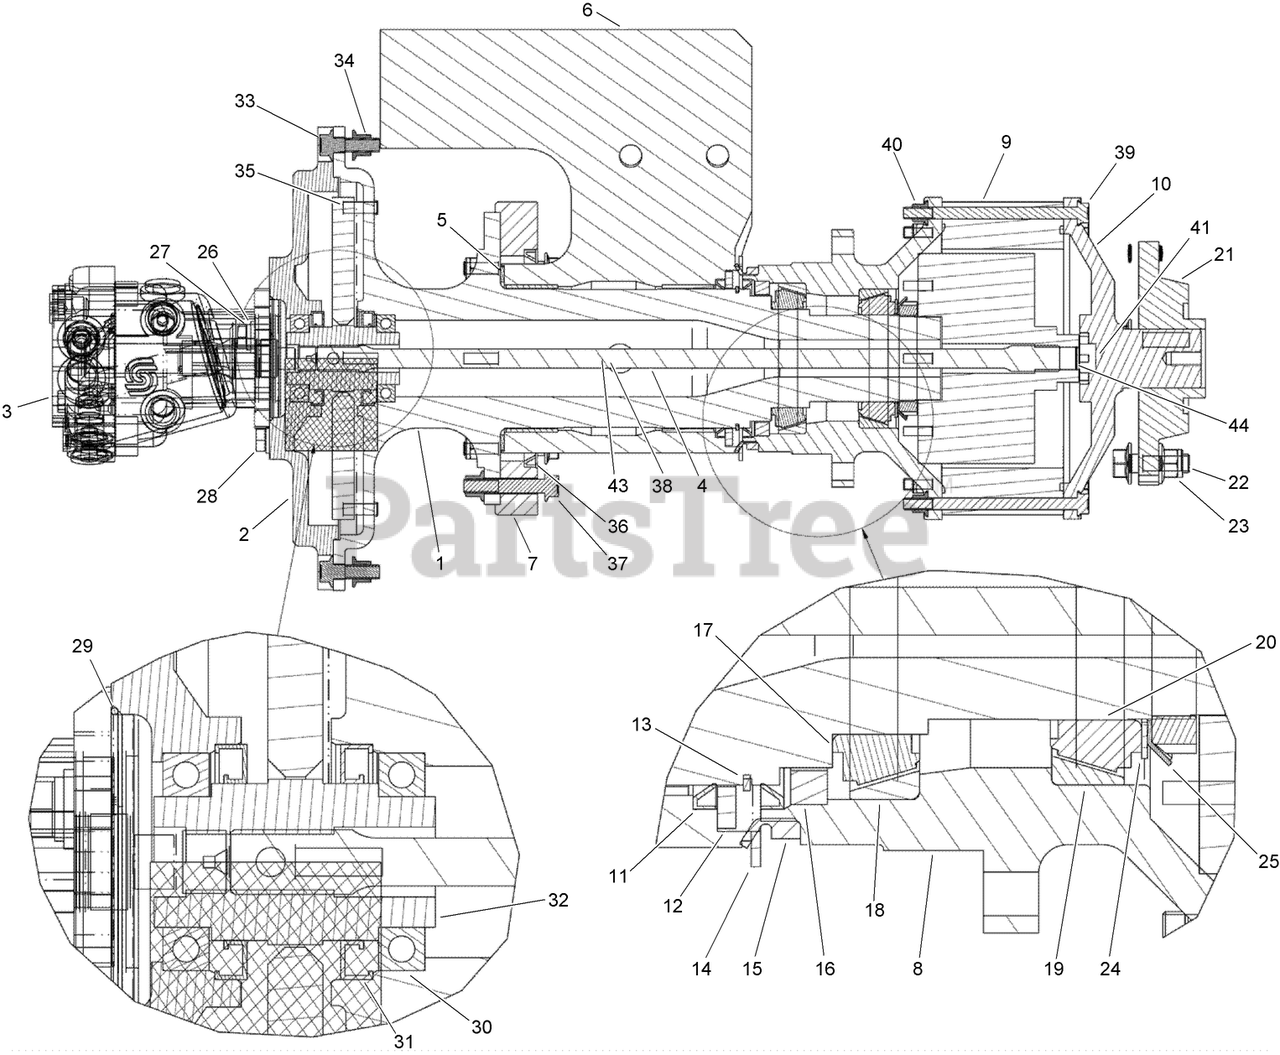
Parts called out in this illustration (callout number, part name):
1	PIVOT-Boom
2	COVER-Flywheel
3	HYD MOTOR ASM
4	SHAFT-DRIVE, TRENCHER
5	WASHER-THRUST, THIN
6	MOUNTING-Boom
7	SPACER-PIVOT, BOOM
8	HUB-Digging Chain Sprocket
9	GEARBOX-Planetary
10	COVER-Planetary
11	SEAL-Urethane
12	WASHER-THRUST, THICK
13	RING-RETAINING, EXTERNAL
14	RING-WEAR
15	SEAL-PLANETARY, URETHANE
17	BEARING
18	BEARING
19	CUP-BEARING
20	BEARING-CONE
21	BEARING
22	SCREW-FLANGE
23	NUT-HHF
24	WASHER-Shim
25	WASHER-LOCK, BEARING
27	WASHER-Spring Lock Reg 1/2 ZND
28	BOLT-Hex Hd 1/2 x 1-1/4 GR5 ZND
30	BEARING-Ball
31	SEAL-Flywheel
32	FLYWHEEL-DRIVE, TRENCHER
34	NUT-HHF, LOCK
35	SCREW-HHF
36	SEAL-URETHANE
37	SCREW, METRIC FLANGE w/BODY-M12 x 70
38	FITTING-Lube 1/8-27 Dryseal PTF
39	SCREW-HSH
40	NUT-FLANGE, NYLOCK
41	PLUG-PIPE
43	PLUG-FREEZE
44	RING-Retaining Int Basic #75 Pln
